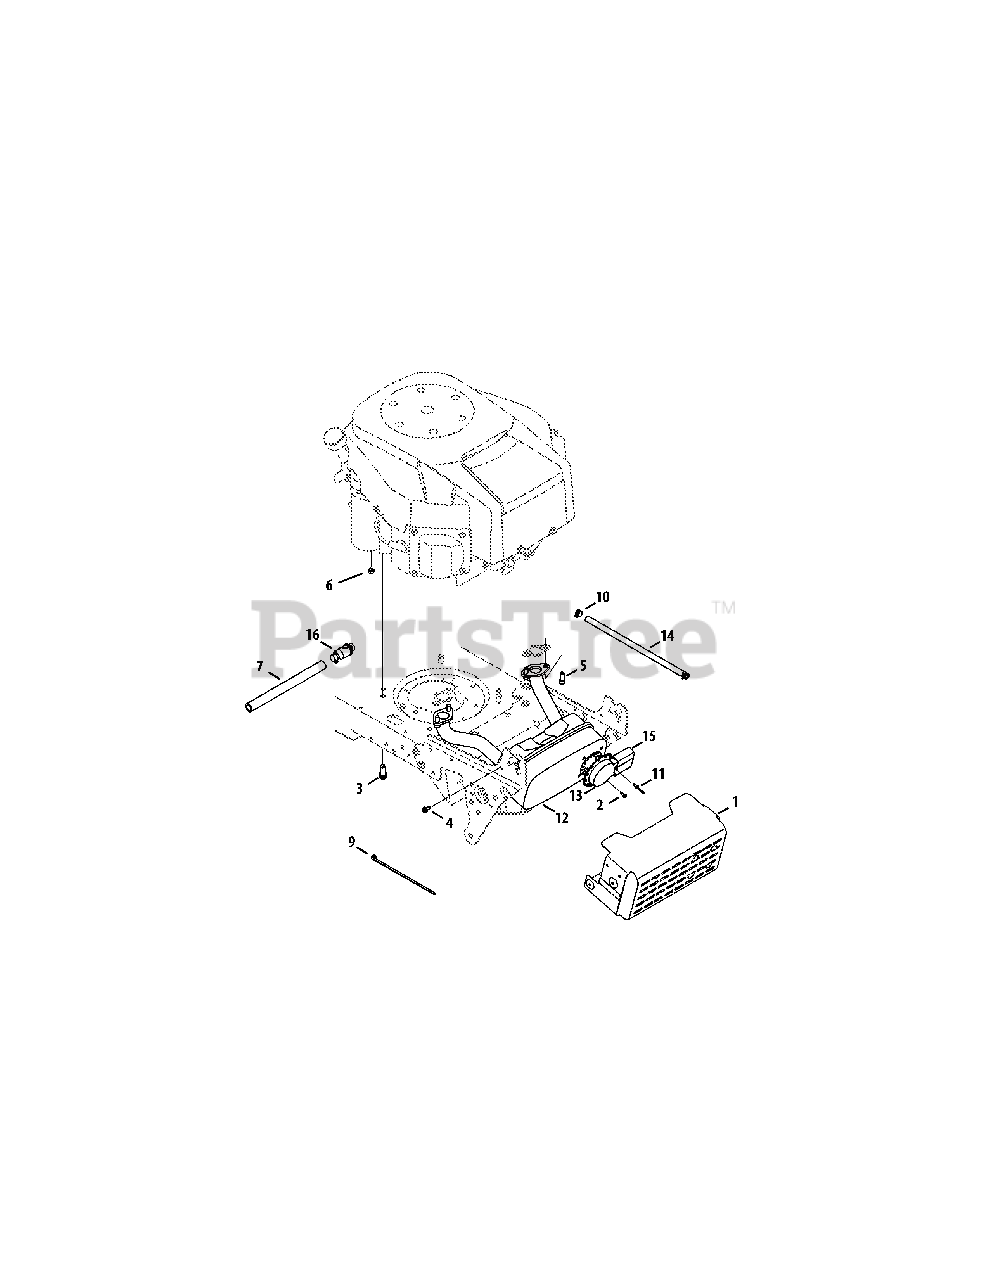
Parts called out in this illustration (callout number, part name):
1	Shield Ass’y, Muffler
2	Screw, Ab, #8-18, 0.500,
3	Screw, Self-tapping, 3/8-16, 1.000,
4	Screw, Self-tapping, 1/4-20, 0.500,
5	Screw, Socket Head, 5/16-18, .750
6	Nut, Sems, 1/4-20
7	Hose, Extension, Oil Drain
9	Cable, Tie, 3/16 x .05 x 7.4
10	Clamp, Hose, .490 Dia.
11	Rivet, Pop, .188 Dia x .300
12	Muffler, Intek Twin
13	Deflector, Muffler
14	Hose, Fuel, Low Permeation, 1/4
15	Deflector, Muffler, Long
16	Drain, Oil
